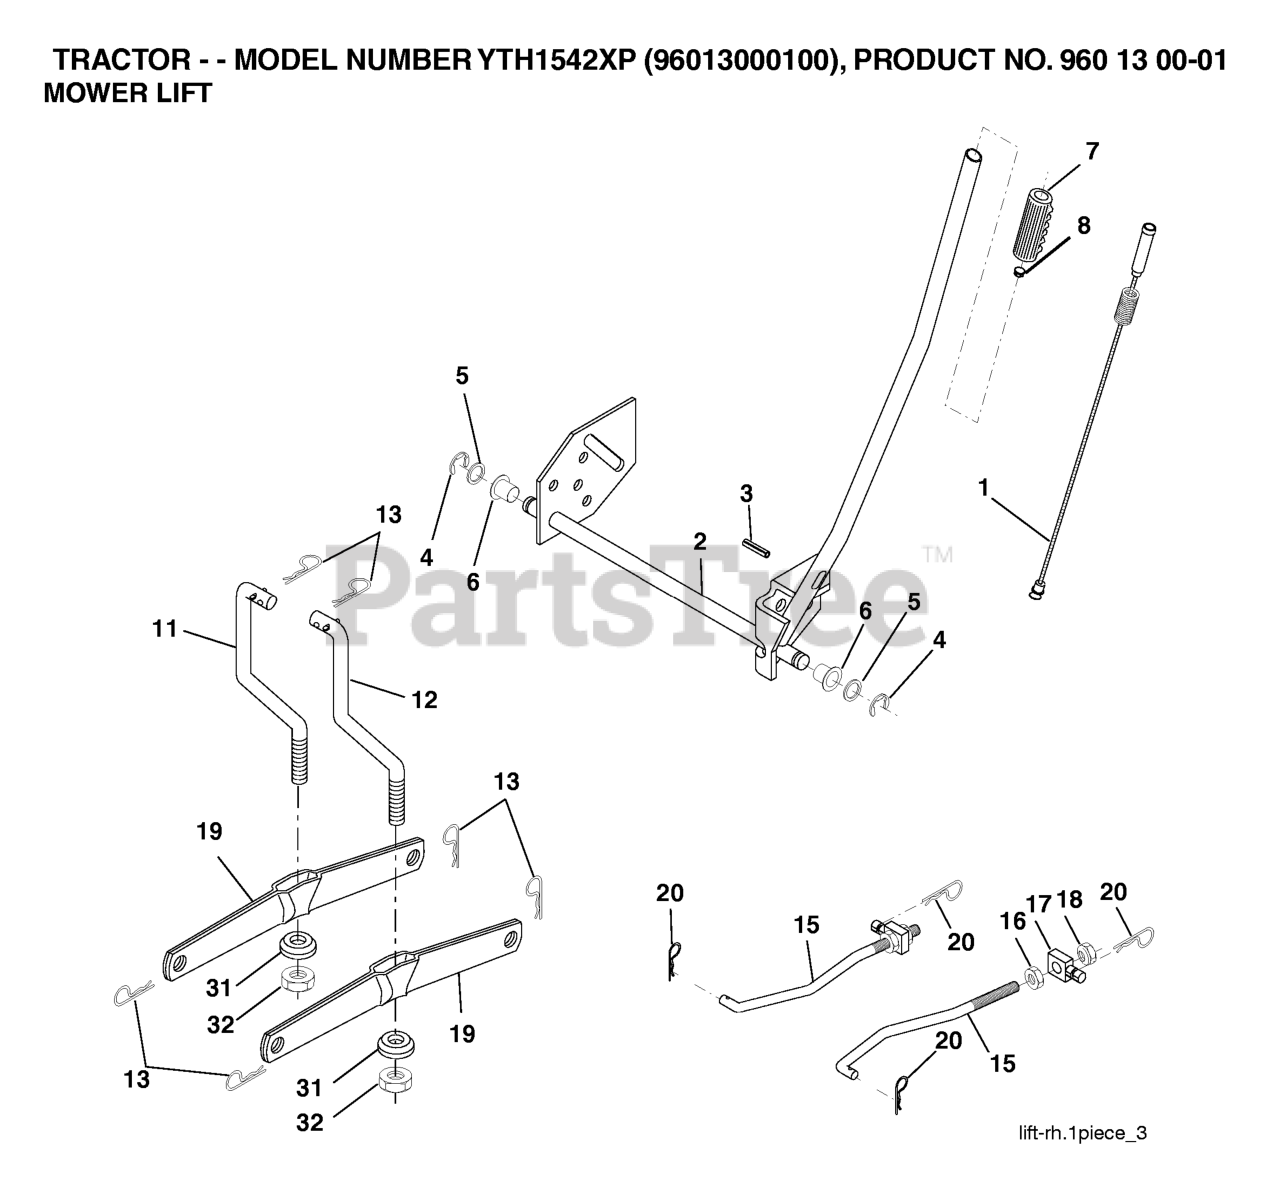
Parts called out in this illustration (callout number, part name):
1	WIRE ASM INNER W/ PLUNGER LT
2	SHAFT ASM R HANDLE
3	PIN GROOVE.
4	RETAINING RING LT
6	BEARING.NYLON
7	GRIP HANDLE
8	PLUNGER BUT KIT
11	LINK LIFT LH
12	LINK LIFT RH
13	RETAINER-SPRNG RB
15	LINK.SUSPENSION.FRONT
16	NUT.HEX.JAM.1/2-13
18	NUT.LK.W/WSH.1/2.
19	ARM.REAR.SUSPENSION
20	SPRING RETAINER
31	BEARING.PIVOT.LIFT
32	NUT CROWNLOCK 3/8-24
